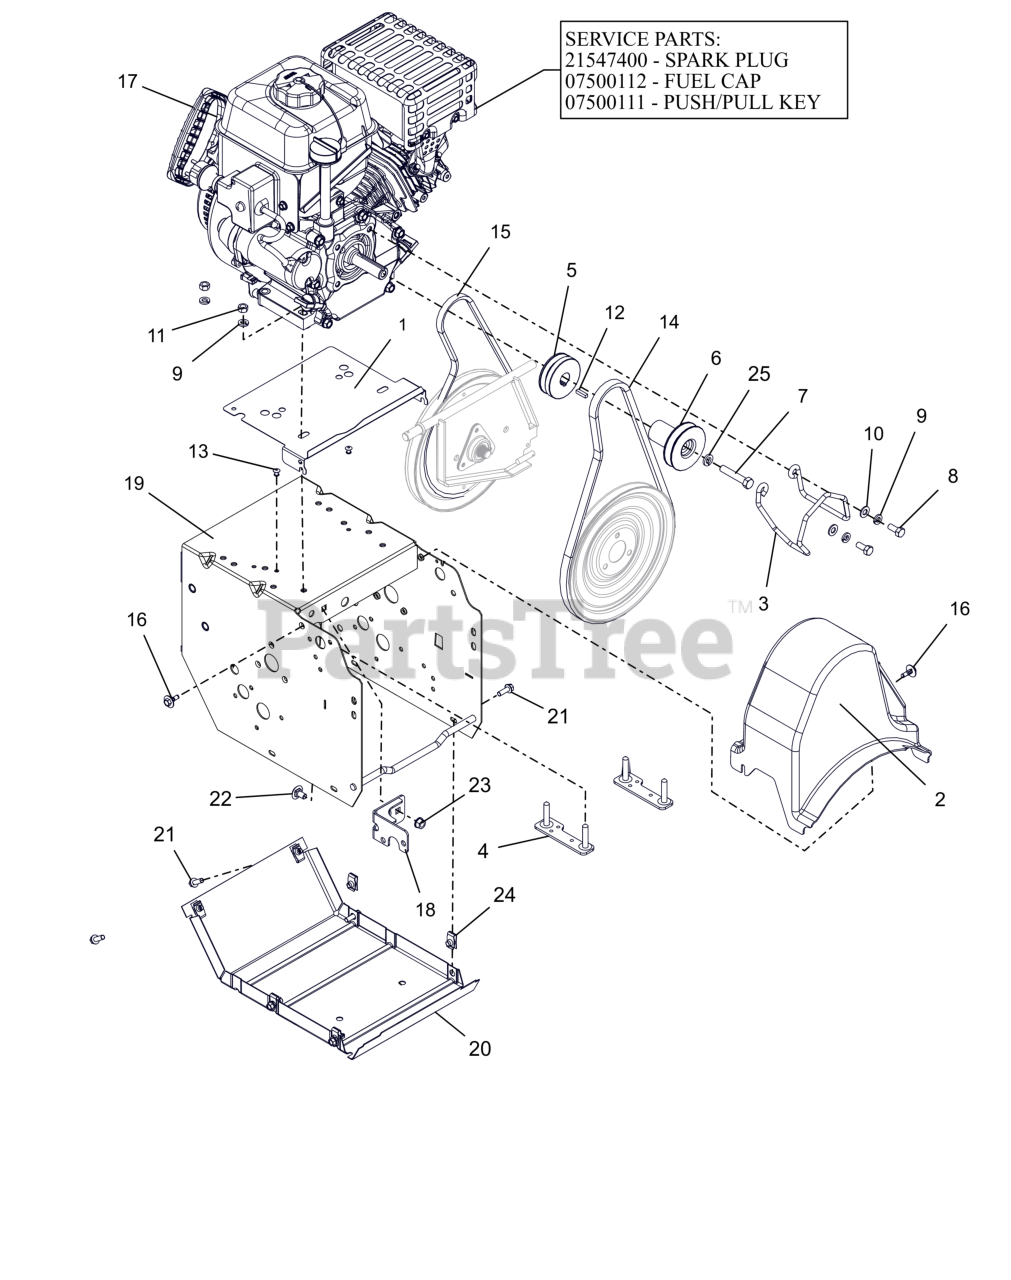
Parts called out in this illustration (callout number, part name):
1	BAFFLE, COMPACT
2	COVER, COMPACT BELT
3	FINGER, BELT
4	STRAP, ENGINE BOLT-WELDMENT
5	SHEAVE, TRACTION-COMPACT TRACK
6	SHEAVE,AUGER 3/4" PM
7	BLT, HEX .38-24X2.00 G5 ZCC
8	BLT, HEX .31-24X.750 G5 ZCC
9	WSHR, LK-HVY .312X.097 ZCC
10	WSHR,FLT .344X.688X.065 ZCC
11	NUT, HEX .312-18 ZCC
12	KEY-SQ .188X.75X.188
13	RVT, POP .1875 ZCC
14	V-BELT, HA-RAW EDGE
15	V-BELT, 3L-WRAPPED
16	SCR-TAP .25-20X.5 CAPTIVE
17	ENGINE, ARIENS AX208 240V/60W
17	PLUG, SPARK
17	CAP, FUEL TANK BLACK
17	KEY, PUSH/PULL LCT (2/PACKAGE)
18	WELDMENT, FRAME BRACKET
19	FRAME, MAIN-WELDMENT
20	COVER, BOTTOM
21	BLT, HWH .25-20X.75 G5 ZCC
22	BLT, RHSSN .31-18X.625 G5 ZCC
23	NUT-LK-TOP-FLG .312-18 GF ZCC
24	NUT-RTNR .25-20X.56
25	WSHR, LK-HVY .375X.115 ZCC
